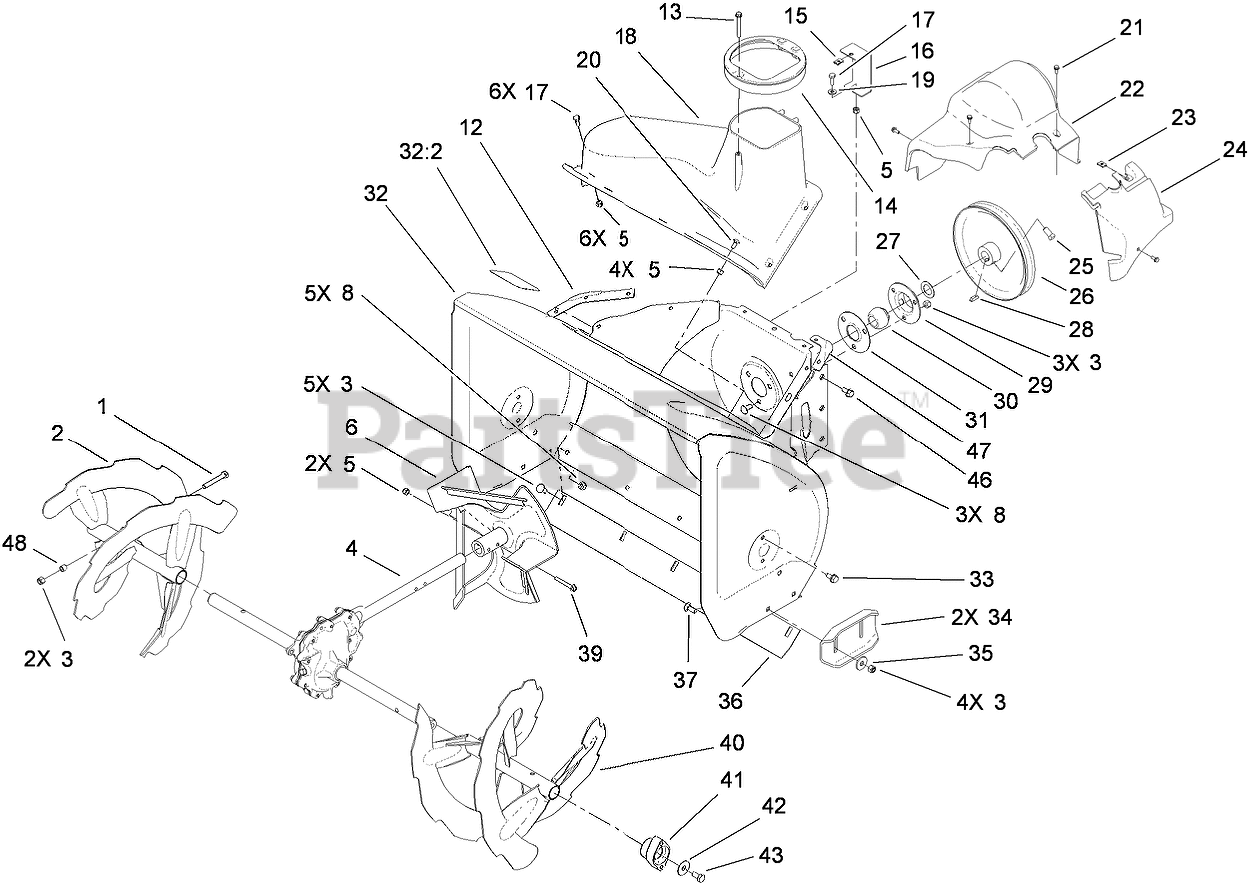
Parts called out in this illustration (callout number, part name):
1	SCREW-HH
2	RH AUGER ASM
3	NUT-LOCK, NI
4	28 INCH AUGER GEARCASE ASM
5	NUT-LOCK, NI
6	IMPELLER ASM
8	SCREW-CARR
12	SEAL-FLANGE, COVER
13	SCREW-PLASTITE
14	GUIDE-CHUTE
15	NUT-SPEED, U-TYPE
16	BRACKET-COVER, CLIP NUT
17	SCREW-HH
19	WASHER-FLAT
20	BOLT-CARR
21	SCREW-HWH
22	COVER-BELT
23	NUT-SPEED
24	COVER-EXTENSION, BELT
25	SCREW-SET, SQH
26	PULLEY-IMPELLER
27	WASHER-THRUST
28	KEY-WOODRUFF
29	FLANGE-CUP, BEARING
30	BEARING-BALL
31	FLANGE-CUP, BEARING
32	HOUSING-AUGER, 28 INCH
32:2	DECAL-DANGER, AUGER
33	SCREW-HWHTF
35	WASHER
36	SCRAPER-FIXED
37	SCREW-CARR
39	SCREW-HHF
40	LH AUGER ASM
41	BEARING-AUGER
42	WASHER
43	SCREW-HH
46	SCREW-HWHTF
48	SPACER
